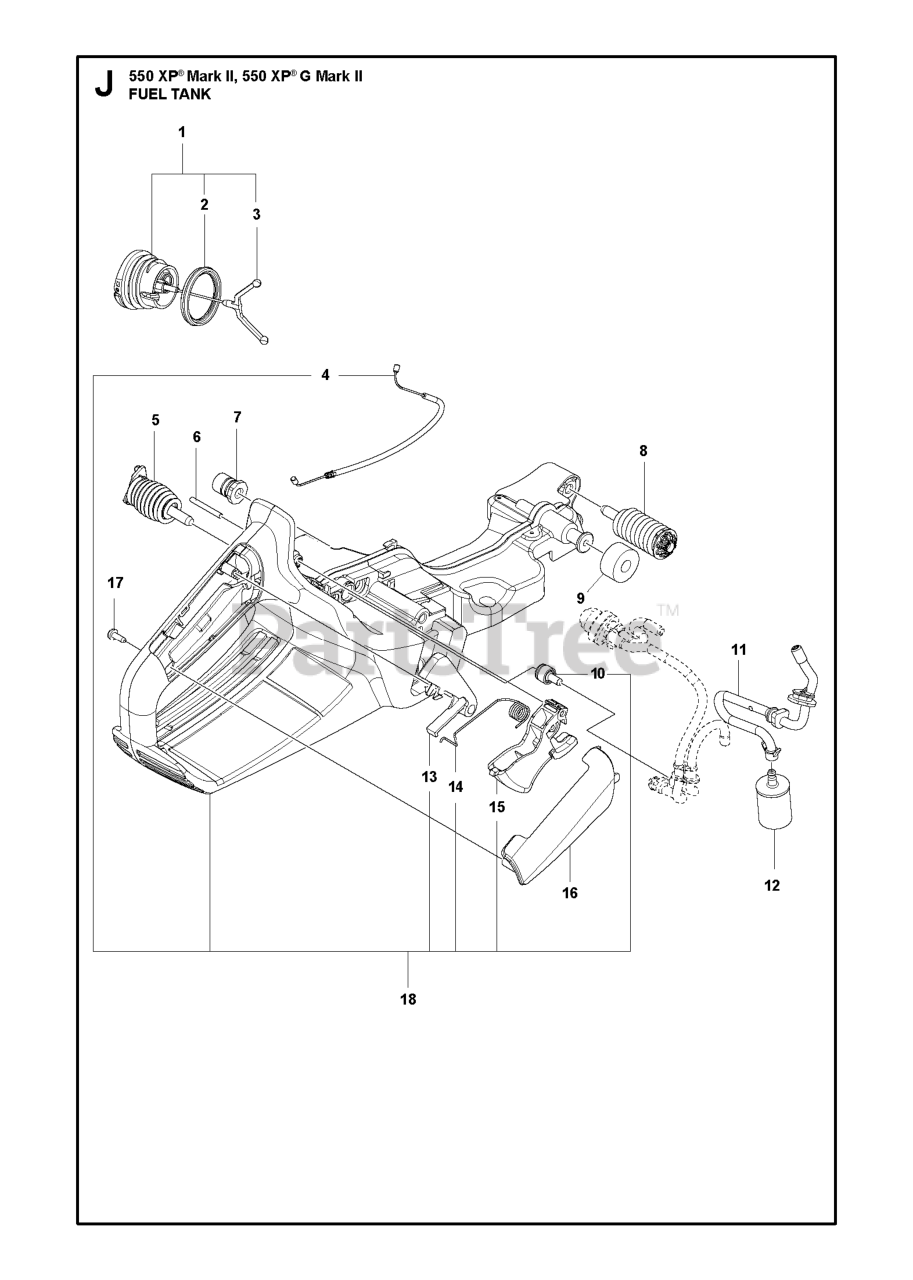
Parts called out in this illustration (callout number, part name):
1	TANK CAP ASSY
4	THROTTLE CABLE ASSY 545/550 M
5	ANTIVIBRATION ELEMENT REAR
7	LATERAL SUPPORT
8	ANTIVIBRATION ELEMENT FRONT
9	DEFLECTION LIMITER
10	FUEL TANK VENT
11	FUEL HOSE
12	RP FUEL FILTER
13	THROTTLE LOCKOUT
16	HANDLE INSERT
17	SCREW CITXPANT
